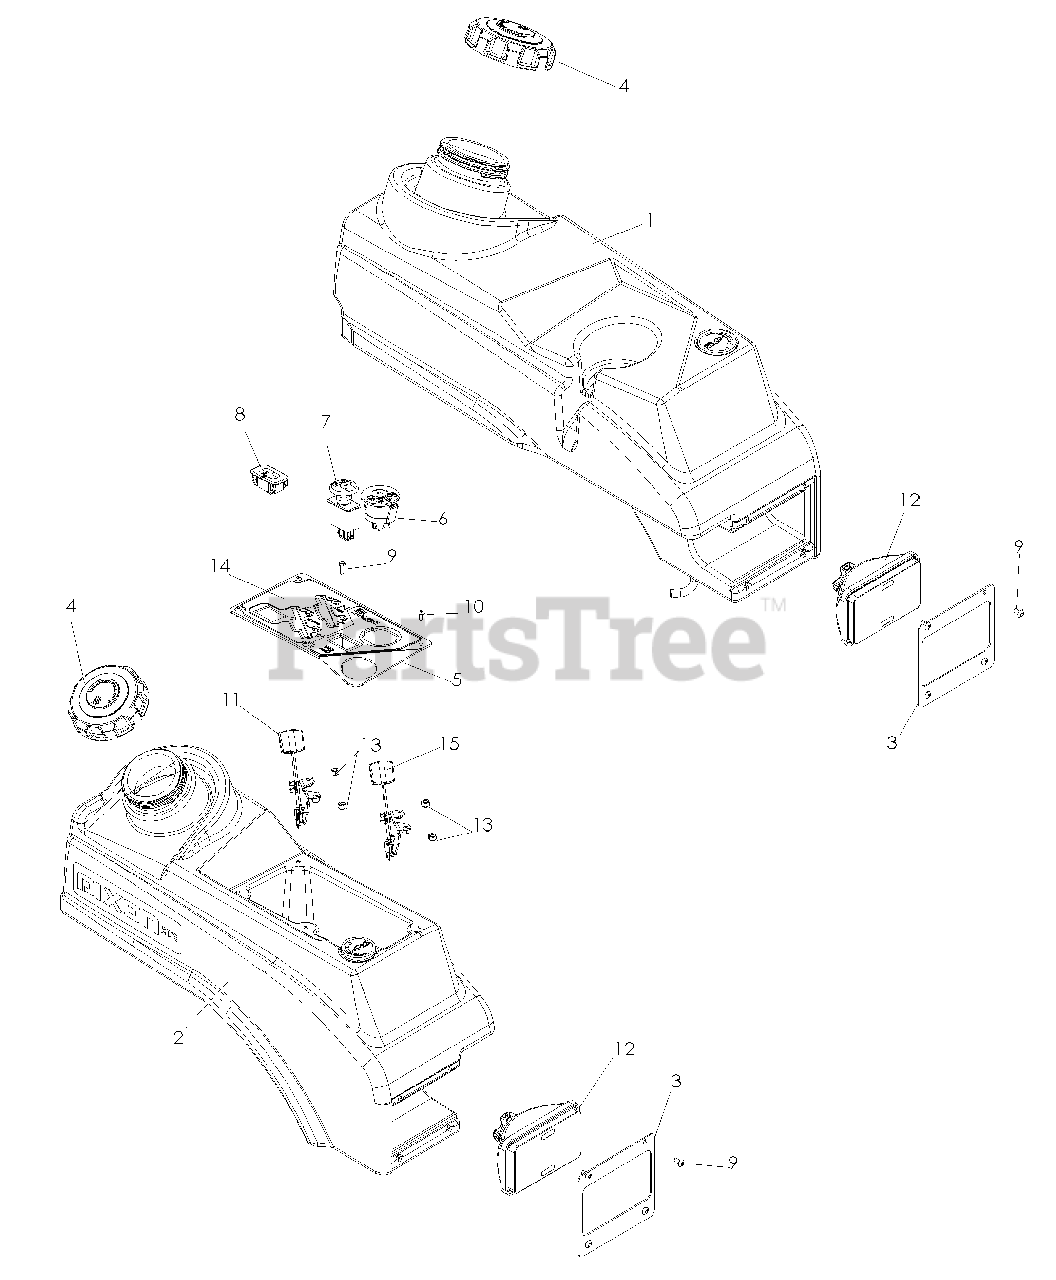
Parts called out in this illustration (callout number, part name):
1	TANK, FUEL, LT
2	TANK, FUEL, RT
3	PLATE LIGHT
4	FUEL CAP ANTI-SPLASH
5	CONTROL PANEL
6	IGNITION SWITCH
7	SWITCH, BLADE
8	HOUR METER
9	HCS #10-24 X 1/2
10	SCR #10-24 X 3/8 SKT HD BLK OX
11	CABLE THROTTLE
13	NUT 10-24 NYLOC
14	DECAL, CONTROL
15	CHOKE CABLE
